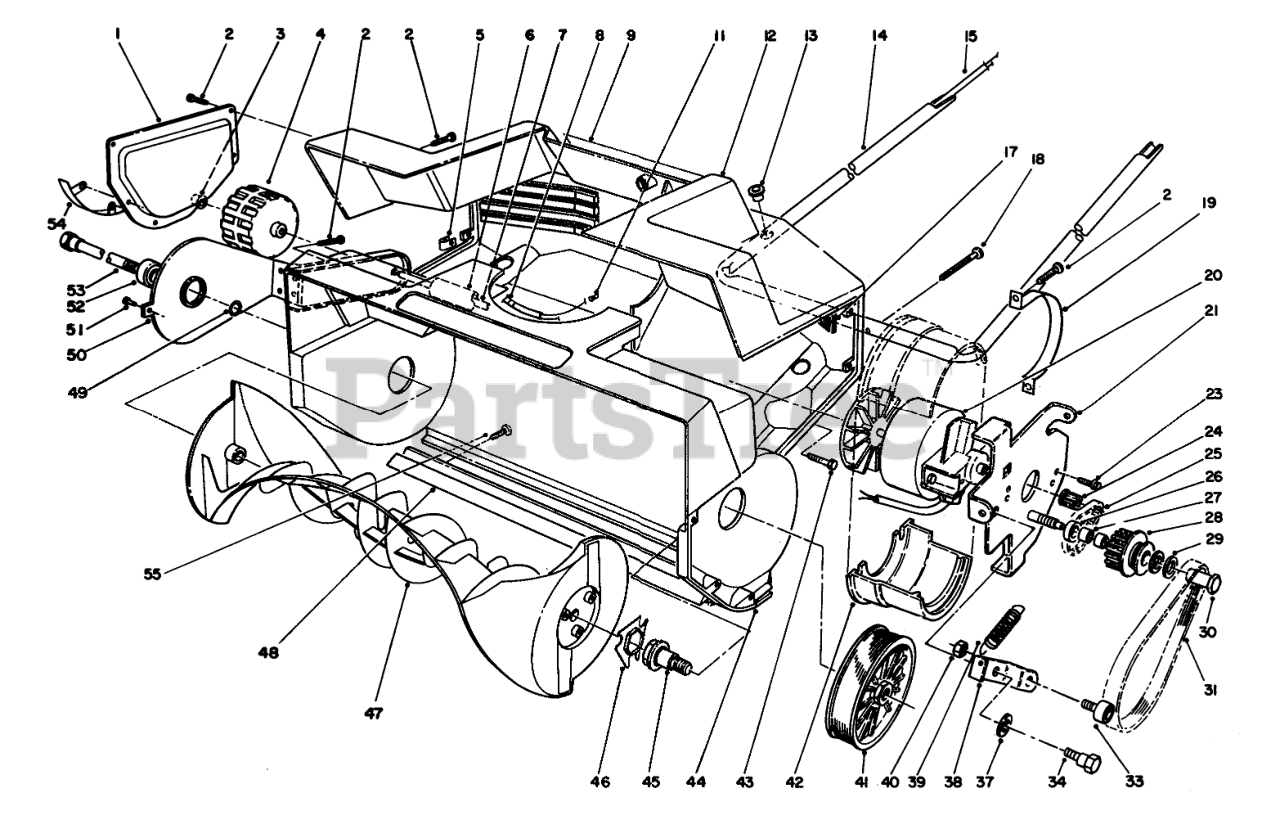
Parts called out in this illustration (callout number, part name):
1	PLATE - SIDE, PAINTED
2	Screw
3	PUSHNUT-CAP, WASHER
4	Wheel
5	U-CLIP
6	SLEEVE, AXLE
7	Shaft-Axle
8	Relief-Strain
9	Decal-Danger
11	Connector
12	SHROUD W/O AMP LABEL
13	BUSHING
14	Tube-Lower Handle
15	Wire Harness
17	Filter-Foam
18	Screw-Pan Head
19	Strap-Motor
20	Motor
21	Motor Plate Assembly
23	Screw-Hex Washer Hd.
24	Pulley-Driver
25	BELT-PULLEY, IDLER/DRIVER
26	WASHER
27	Bearing
28	Pulley Assembly-Idler (Incl. Ref. #27)
29	WASHER-THRUST
30	Bolt-Idler
31	Belt-Drive
33	Bearing Assembly (Incl. Ref. #40)
34	SCREW-SHOULDER
37	WASHER
38	Bracket-Idler
39	Spring
40	NUT-LOCK, NI
41	Pulley-Driven
42	Clamp-Motor Bracket
43	SCREW-HH
44	Housing-Rotor
45	Shaft-Driver, Rotor
46	Coupler-Rotor
47	Rotor
48	Scraper
49	WASHER-THRUST
50	Bracket-Wheel (Incl. Ref. #52)
51	RIVET-POP
52	Bearing-Ball
53	Shaft-Rotor
54	Skid-Housing
55	Screw-Pan Head
